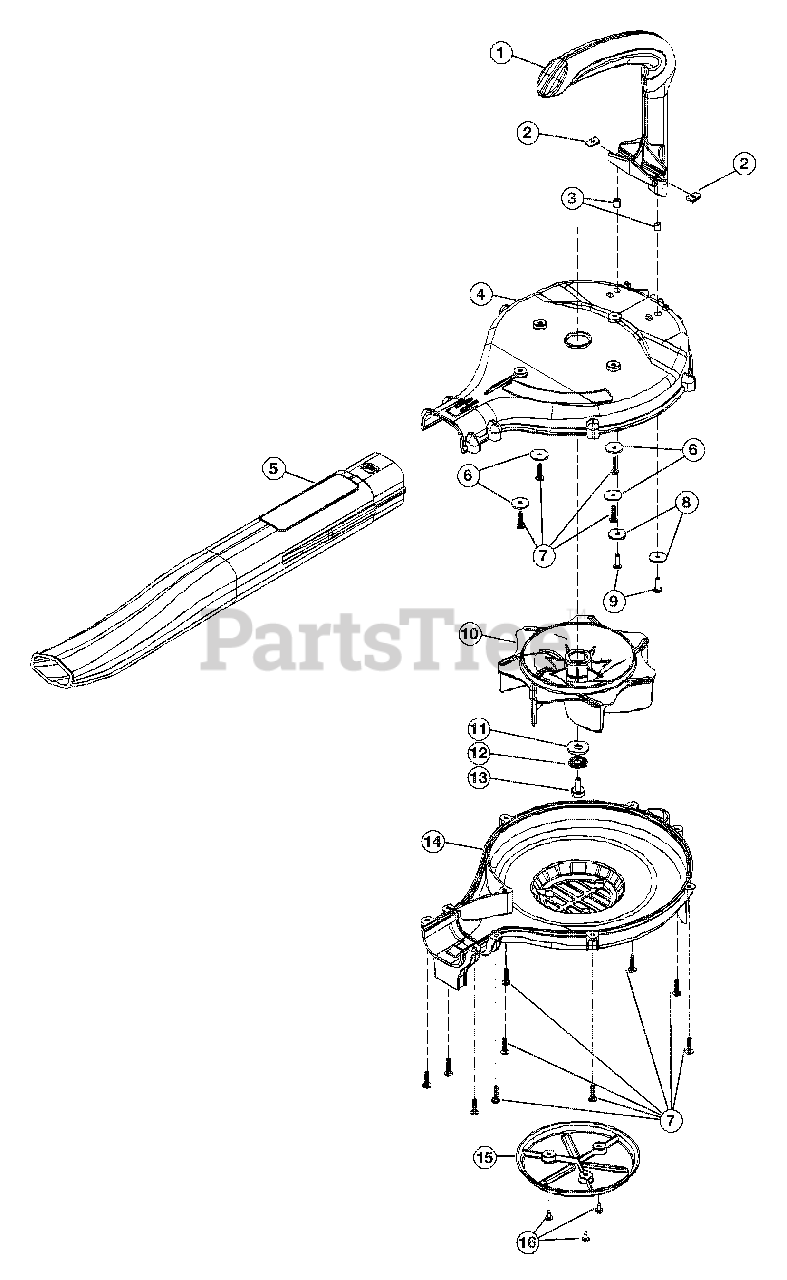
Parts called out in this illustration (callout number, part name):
1	Blower Handle
2	Weldnut
3	Spacer
4	Upper Impeller Housing
5	Blower Tube
7	Housing Screw
8	Handle Washer
9	Handle Screw
10	Impeller
11	Washer
12	Lock Washer
13	Bolt
14	Lower Impeller Housing
15	Intake Deflector
16	Deflector Screw
